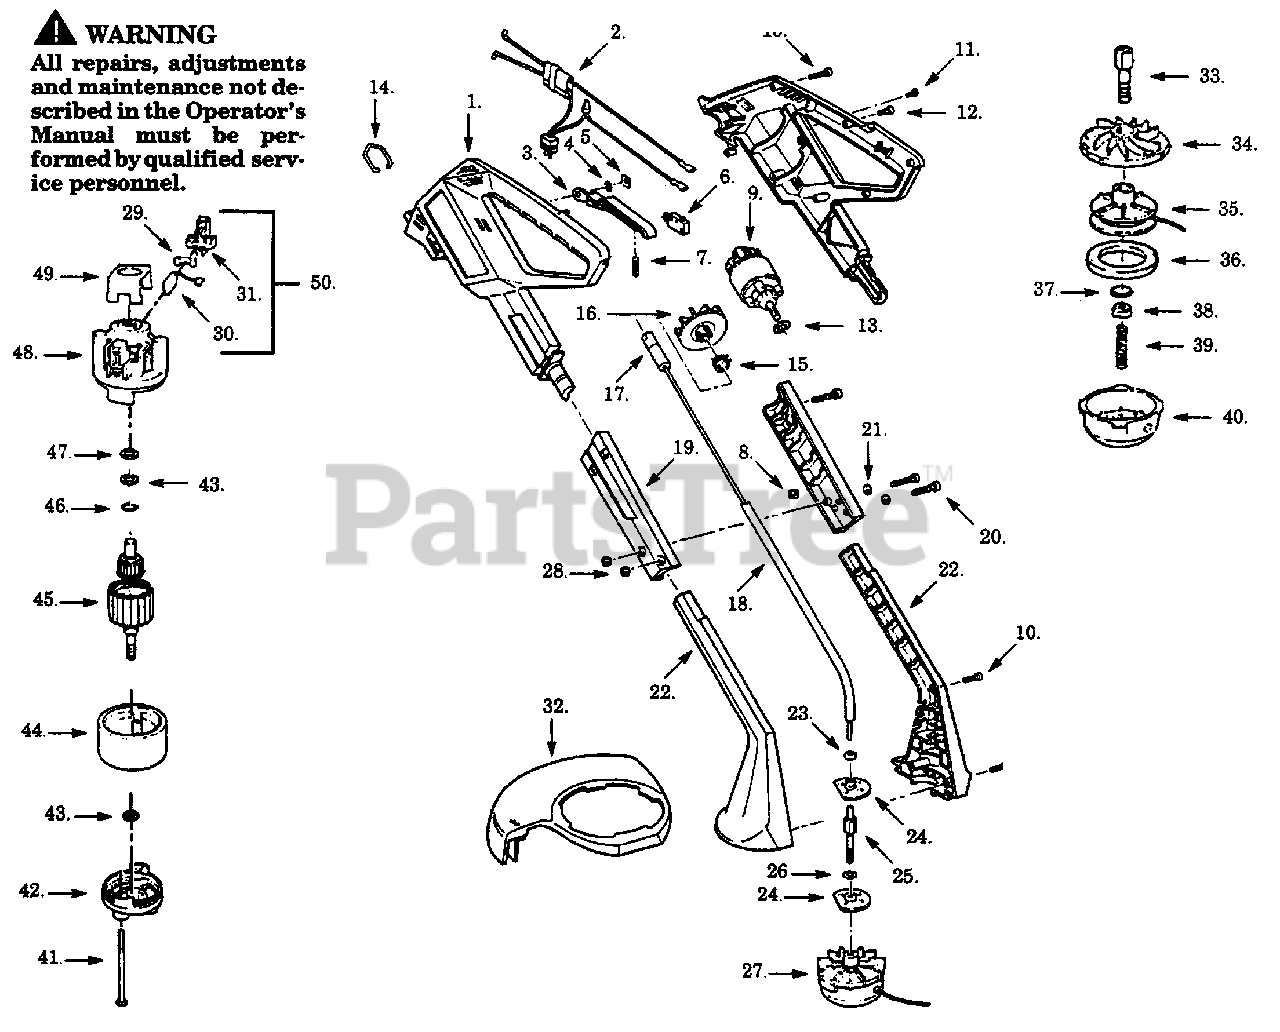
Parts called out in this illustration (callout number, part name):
1	Motor Hsg. Set
5	Push Nut
7	Trigger Spring
8	Square Nut
9	Motor Ass'y.
15	Fan Clamp
17	Flex Shaft Ass'y.
18	Sleeve Tubing
19	Housing Clamp
22	Spindle Housing
24	Bearing Holder Disk
25	Shaft Adapter
27	Head Ass'y. (Model 1000C)
27	Head Ass'y. (Model 1200C)
29	Brush Spring
31	Brush Holder
32	Guard Ass'y. (Model 1000C)
32	Guard Ass'y. (Model 1200C)
33	Shaft Adapter
34	Rear Plate
35	Spool & Line (Model 1000C)
35	Spool & Line (Model 1200C)
36	Foam Pad
38	Adapter Nut
40	Hub Ass'y. (Model 1000C)
40	Hub Ass'y. (Model 1200C)
42	Endbell Ass'y. (Drive)
44	Field Ass'y.
45	Armature Ass'y.
46	Retaining Ring
48	Endbell Ass'y. (Brush)
49	Insulator
50	Brush Kit (Incl. 29,30,31)
